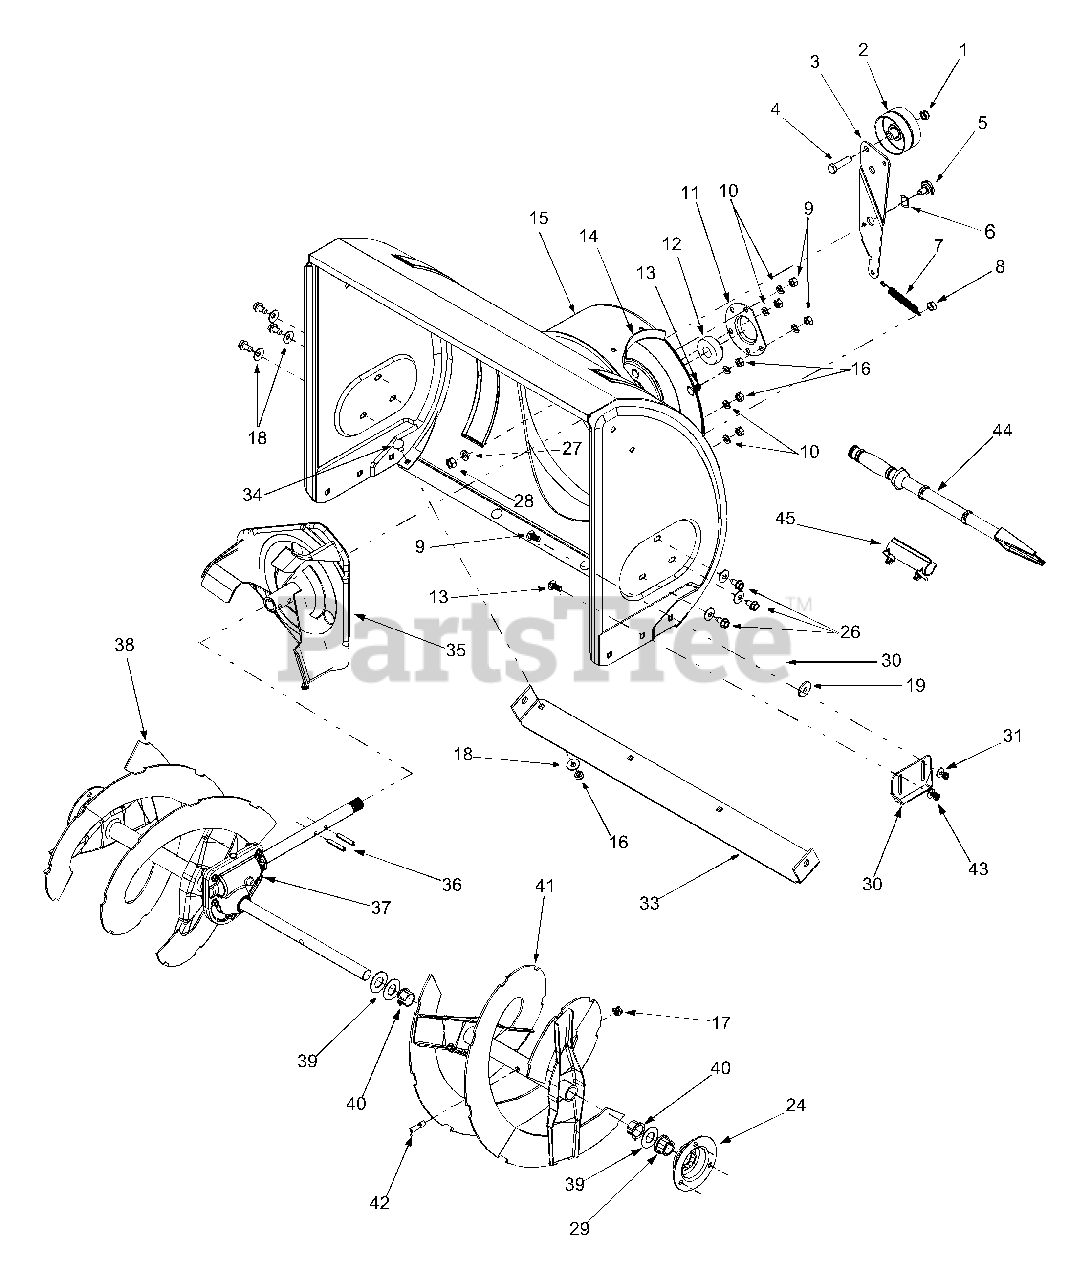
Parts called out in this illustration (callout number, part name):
1	Lock Jam Nut 3/8-24
2	Flat Idler
4	Hex Cap Screw 3/8-24 x 1
5	Shoulder Screw
6	Wave Washer
7	Extension Spring
8	Hex Nut 5/16-18
9	Carriage Bolt, 5/16-18 x 1.00
10	Lock Washer 5/16
11	Bearing Housing
12	Ball Bearing
13	Carriage Bolt, 5/16-18 x .75
17	Lock Nut 5/16-18
18	Belleville Washer
19	Flat Wshr, .344ID x 1.125 OD
26	Hex Screw 5/16-18 x .75
27	Lock Washer 3/8
28	Hex Nut 3/8-16
29	Hex Flange Bearing
31	Bell Washer
32	Hex Nut 5/16-18
34	Carriage Bolt 5/16-18 x .75
37	30" Auger Gearbox Assembly
39	Flat Washer
40	Flange Bushing
43	Hex Nut 5/16-18
44	Clean-Out Tool
45	Clean-Out Tool Mount
